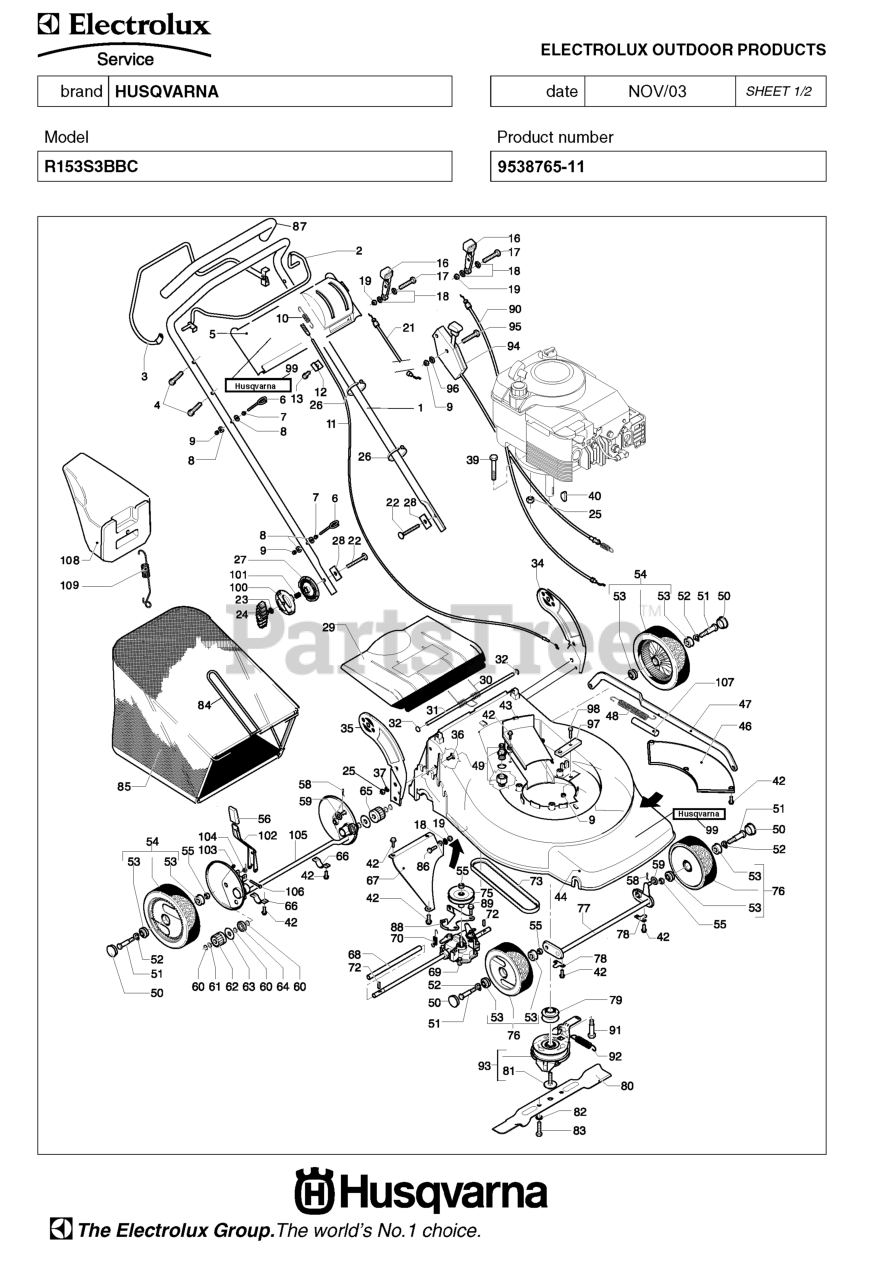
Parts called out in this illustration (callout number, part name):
42	Screws
58	Pins
60	Washers
